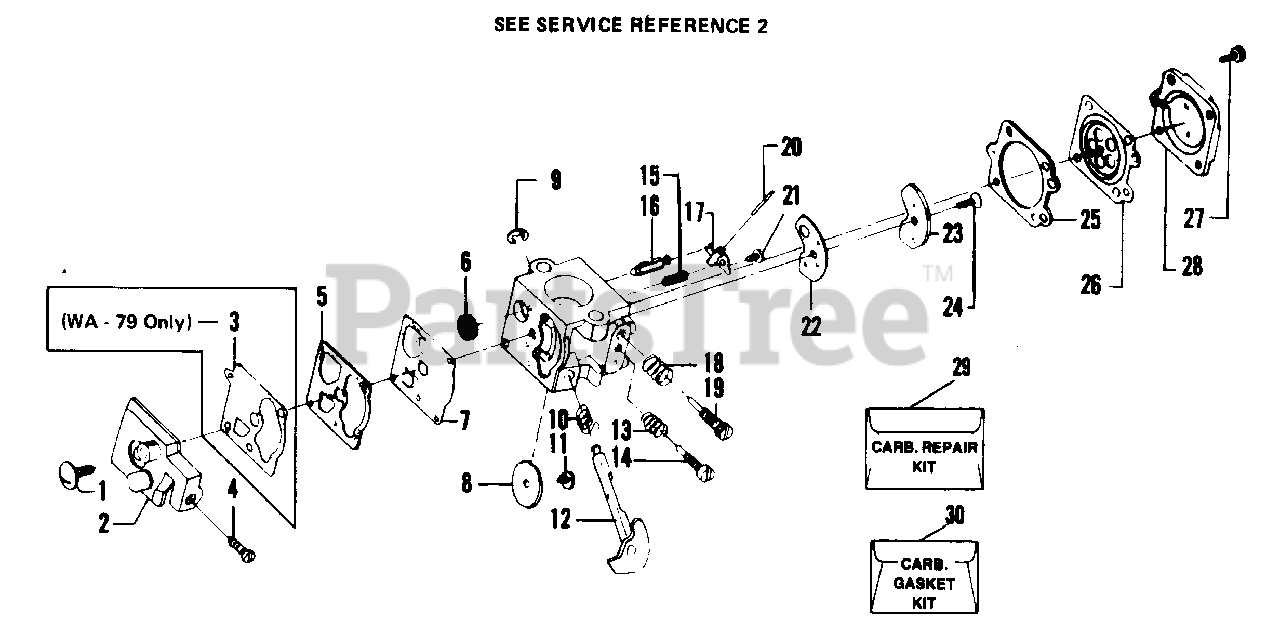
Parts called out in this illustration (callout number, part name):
1	Screw - Pump Cover
2	Pump Cover Ass'y (Inc. # 4) WA-79
2	Pump Cover Ass'y (Inc. # 4) WA-149
3	Diaphragm - Pump (WA-79)
4	Screw - Idle Adjustment
5	Gasket - Pump WA-79
5	Gasket - Pump WA-149
6	Screen - Inlet
7	Diaphragm - Pump WA-79
7	Diaphragm - Pump WA-149
8	Valve - Throttle
9	Clip - Throttle Shaft
10	Spring - Throttle Return
11	Screw - Throttle Valve
12	Shaft Assembly - Throttle
13	Spring - Idle Needle
14	Needle - Idle
15	Spring - Metering Lever
16	Valve - Inlet Needle
17	Lever - Metering
18	Spring - Hi Speed Needle
19	Needle - Hi Speed
20	Pin - Metering Lever
21	Screw - Metering Lever Pin
22	Gasket - Circuit Plate
23	Plate - Circuit
24	Screw - Circuit Plate
25	Gasket - Metering Diaphragm
26	Diaphragm Assembly - Metering
27	Screw - Assembly - Metering Cover & Throttle Shaft Clip
28	Cover - Metering Diaphragm
29	Kit - Carb. Repair
30	Kit - Carb. Gasket/Diaphragm WA-79
30	Kit - Carb. Gasket/Diaphragm WA-149
